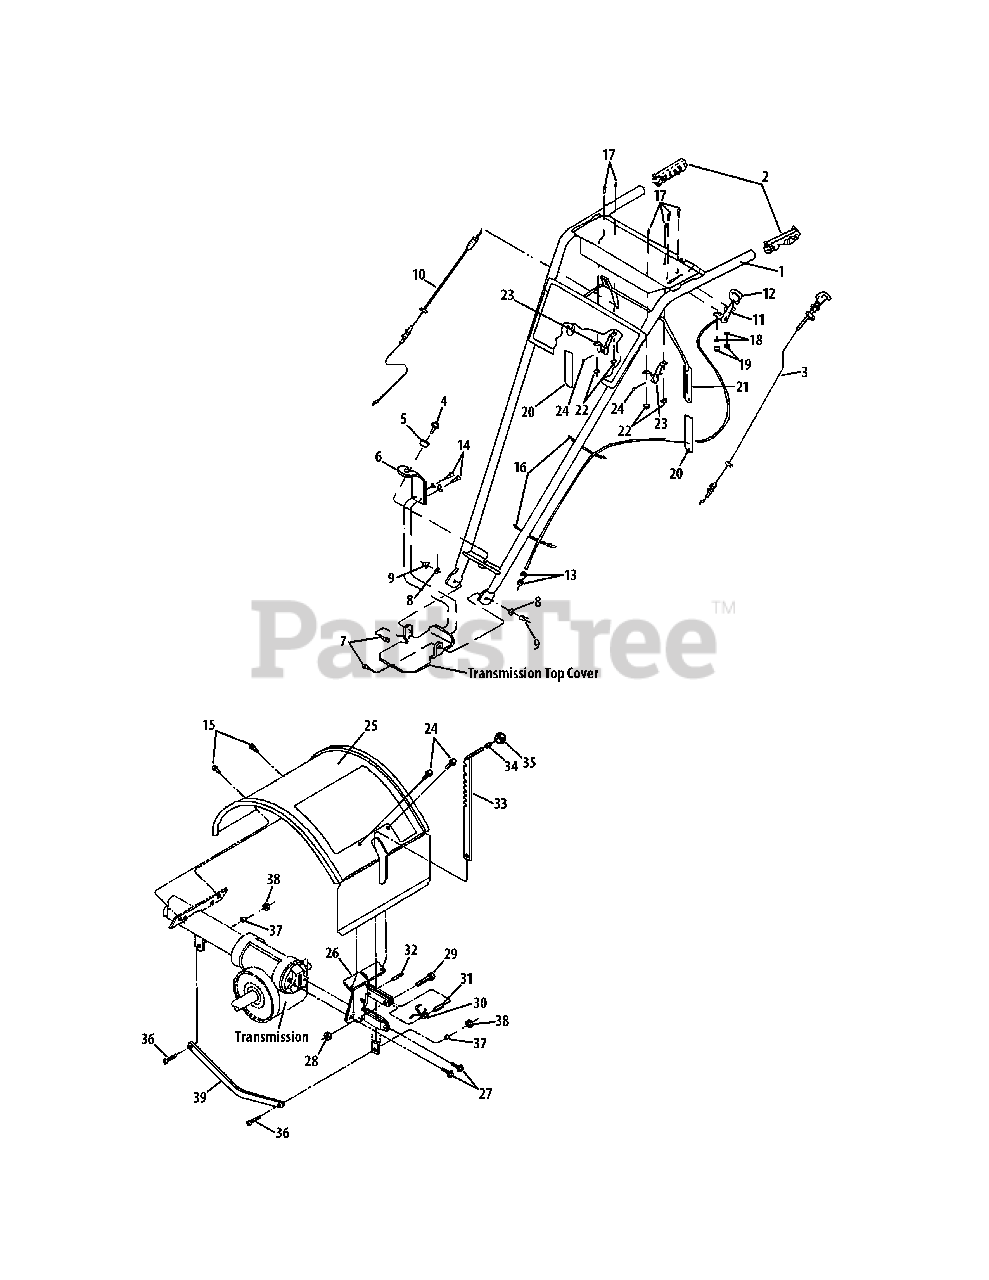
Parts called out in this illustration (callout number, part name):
1	Handlebars
3	Reverse Clutch Control Cable
4	Hex Flange Screw, 3/8-16
5	Keyed Washer
6	Handlebar Hgt. Adjustment Bracket
7	Hex Hd. Screw, 3/8-16 x 1
8	Plain Washer, 3/8
9	Hex Locknut, 3/8-16
10	Forward Clutch Control Cable
11	Wheel Gear Control & Cable Ass.
12	Wheel Gear Control Lever Knob
13	Hex Nut, 5/16-24
14	Self-tapping Screw, 3/8-16 x 3/4
15	Self-tapping Screw, 5/16-18 x 5/8
16	Cable Ties
17	Round Head Screw, #10-32 x 1/2
18	Lockwasher, #10
19	Hex Nut, #10-32
21	Forward Clutch Bail
23	Bail Support Bracket
24	Self-tapping Screw, 1/4-20 x 1/2
26	Depth Regulator
27	Hex Flange Screw, 5/16-18 x 5/8
28	Hex Locknut, 1/4-20
29	Hex Head Screw, 1/4-20 x 1
32	Roll Pin (spiral), 1/4 x 1
33	Depth Regulator
34	Retaining Ring
35	Depth Regulator Knob
36	Hex Head Screw, 3/8-16 x 1-1/4
37	Drag Bar Bushing
38	Hex Nut, 3/8-16
